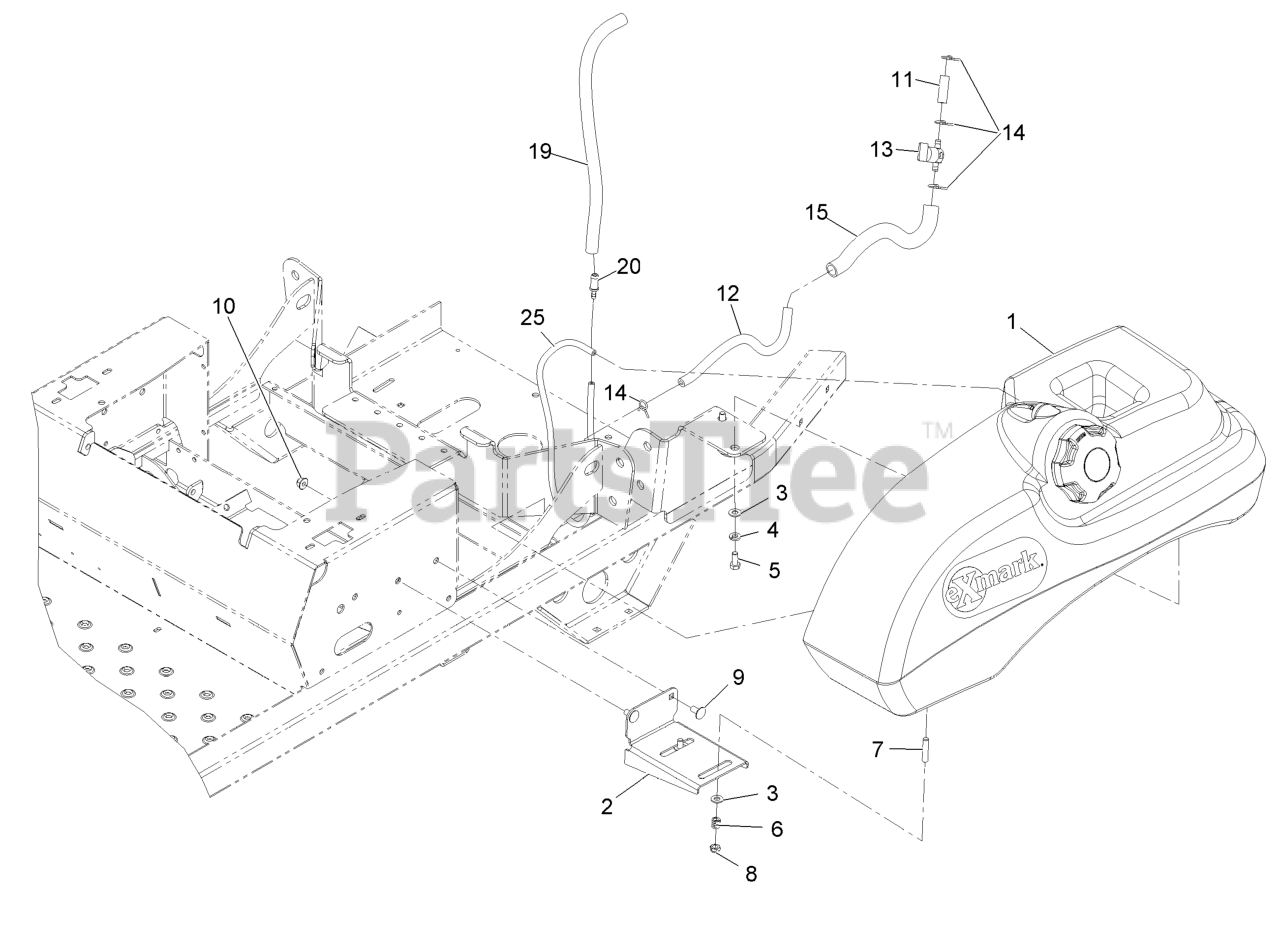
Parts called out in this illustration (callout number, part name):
1	ASM-FUEL TANK
2	BRACKET-TANK AND FENDER
3	WASHER-PLAIN
4	WASHER-LOCK
5	SCREW-HH
6	SPRING-TANK, FUEL
8	NUT-LOCK, NI
9	SCREW-CARR
10	NUT-HF, NI
11	HOSE-FUEL
12	HOSE-FUEL
13	VALVE-FUEL
15	CONDUIT-FUEL LINE
19	HOSE-FUEL
20	FITTING-ORIFICE, STRAIGHT
25	HOSE,EMISSIONS
